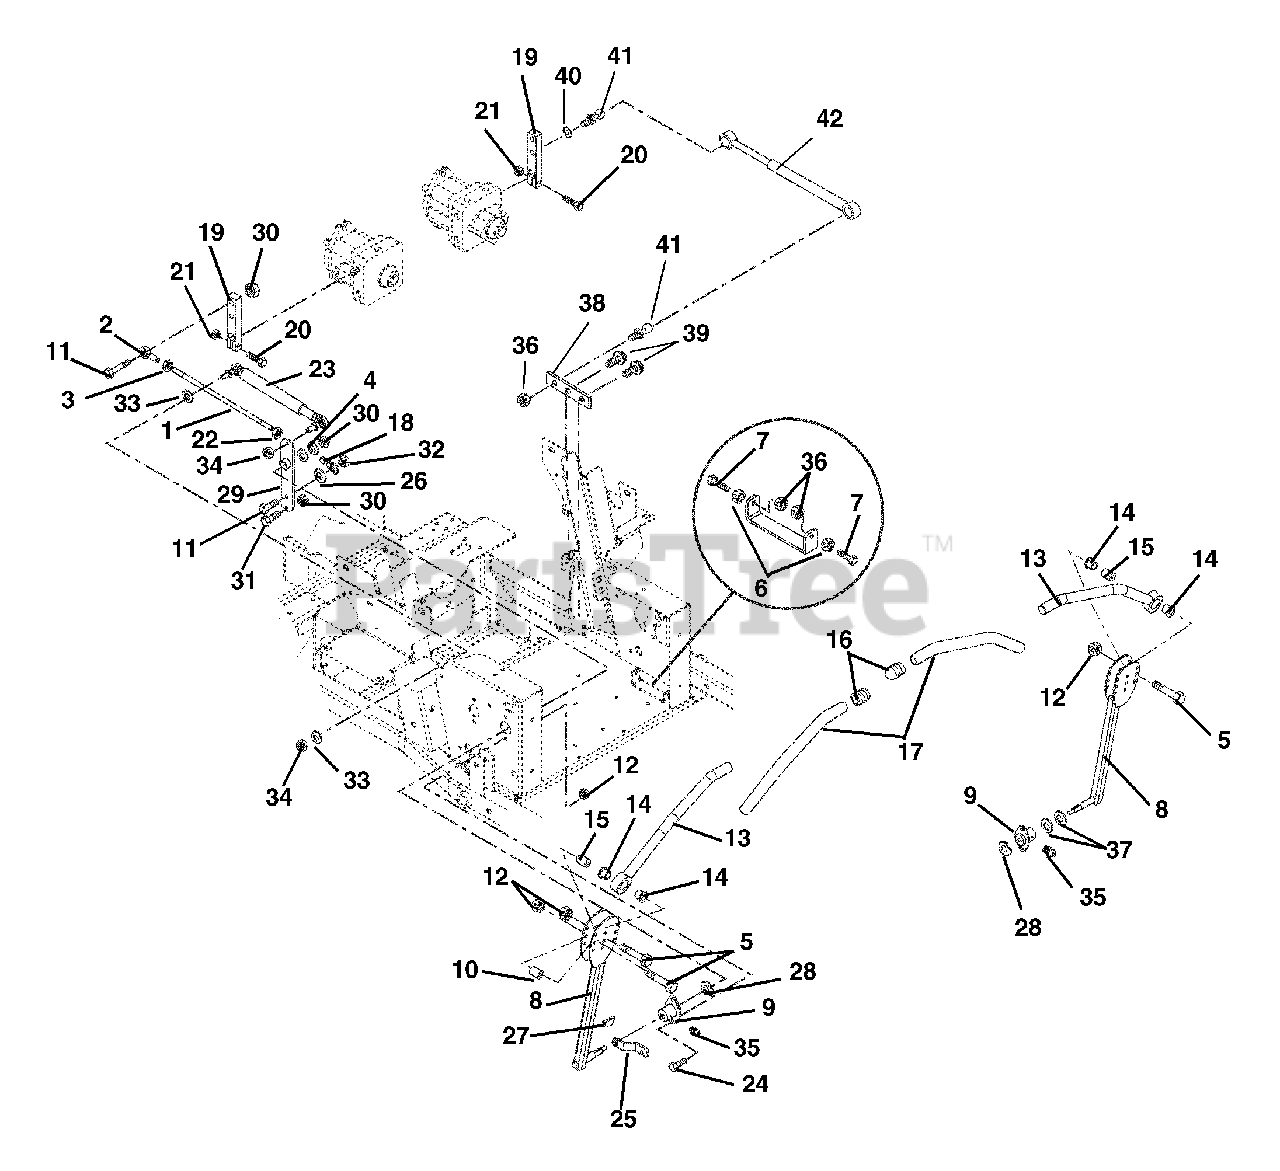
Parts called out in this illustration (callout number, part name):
1	Tie Rod Assembly
2	Rod End, .38 Right Hand
3	Nut-Jam .375-24
4	Washer-Flat-Steel .38 x .875 x .083
5	Bolt-Hex .31-18 x 1.75 Grade 5
6	Nut-Jam .312-18
7	Bolt-Hex .31-18 x 1.50 Grade 2
8	Weldment, Control Arm
9	Bushing-Flange .515 x .750 x .745 x 1.00
10	Eccentric
11	Bolt-Hex .38-16 x 1.75 Grade 5
12	Nut-Locking-Nylon .312-18
13	Handle Weldment Left-Hand
13	Handle Weldment Right-Hand
14	Bushing-Flange-Nylon .762 x 1.48 x .44
16	Caplug- Handlebar
17	Grip-Handlebar
18	Rod End, .38 Left Hand
19	Arm, Pump Actuating
20	Bolt-Hex .25-20 x 1.25 Grade 5
21	Nut-Locking-Nylon .250-20
22	Nut-Jam .375-24 Left Hand
23	Dampener, Self-Centering
24	Bolt-Hex .31-18 x .75 Grade 5
25	Footboard, Lock-Up
26	Washer-Locking .38 x .094 Regular
27	Key-Woodruff .13 x .63
28	Wave Washer
29	Weldment, Pivot Arm
30	Nut-Locking-Nylon .38-16
31	Bolt-Hex .38-16 x 1.25 Grade 5
32	Nut-Locking Top .375-16 Grade C
33	Washer-Flat-Steel .38 x .875 x .083
34	Nut-Locking-Nylon M8-1.25
35	Fitting-Lube .25-28 x .256
36	Nut-Locking-Center .31-18
37	Washer-Flat-Steel .63 x 1.005 x .062
38	Bracket, Damper Mounting
39	Screw-Tapping .31-18 x .75 Hex Washer Head
40	Washer-Locking .31 x .078
41	Stud- Ball
42	Damper, Control
